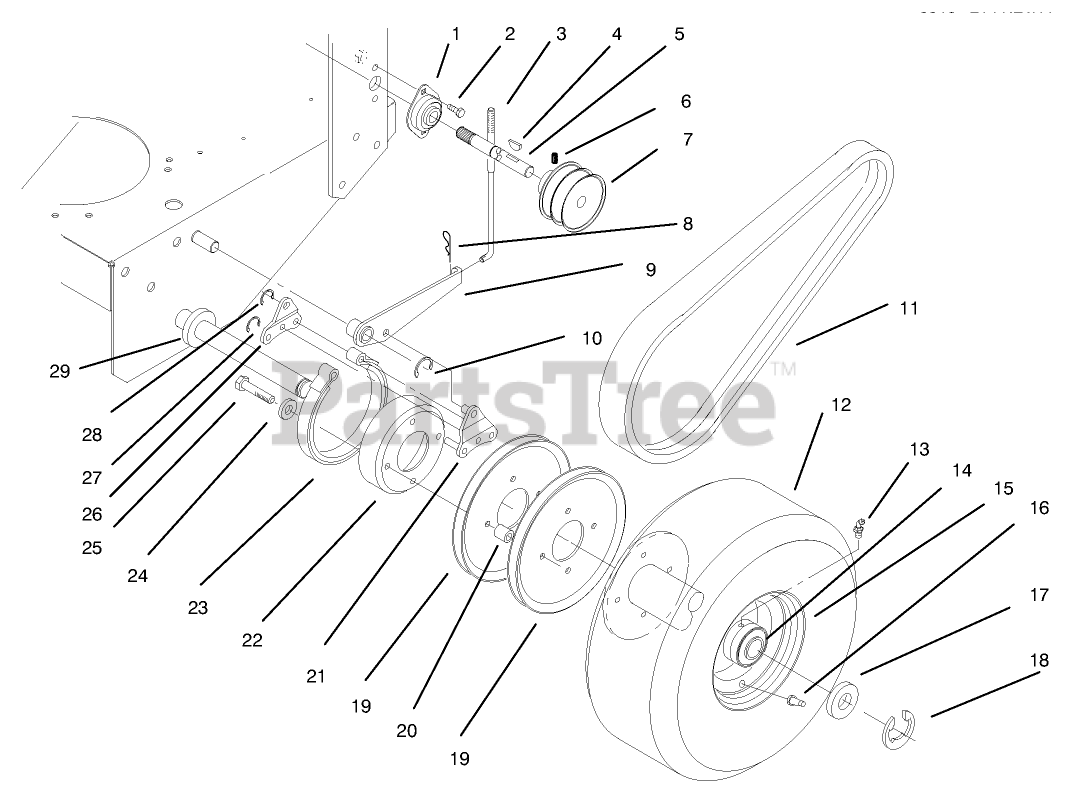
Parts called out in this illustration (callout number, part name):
1	BEARING-EXTERNAL SHAFT
2	SCREW-HH
3	ROD-BRAKE
4	KEY-WOODRUFF
5	SHAFT-EXTENSION, RH
6	SCREW-SET, HS
7	Pulley-Drive
8	PIN-COTTER
9	Brake Arm-LH
10	RING-RETAINING
11	V-BELT
13	FITTING-LUBE, 45 DEG
14	BEARING-BALL
15	WHEEL AND HUB ASM
16	STEM-VALVE
17	WASHER-THRUST
18	RING-RETAINING
19	Pulley-Wheel
20	SPACER-PULLEY
21	LINK-Brake
22	Drum-Brake
23	BAND-BRAKE
24	WASHER-LOCK
25	SCREW-HH
26	Plate-Link
27	RING-RETAINING
28	RING-RETAINING, EXTERNAL
29	WASHER-WHEEL
